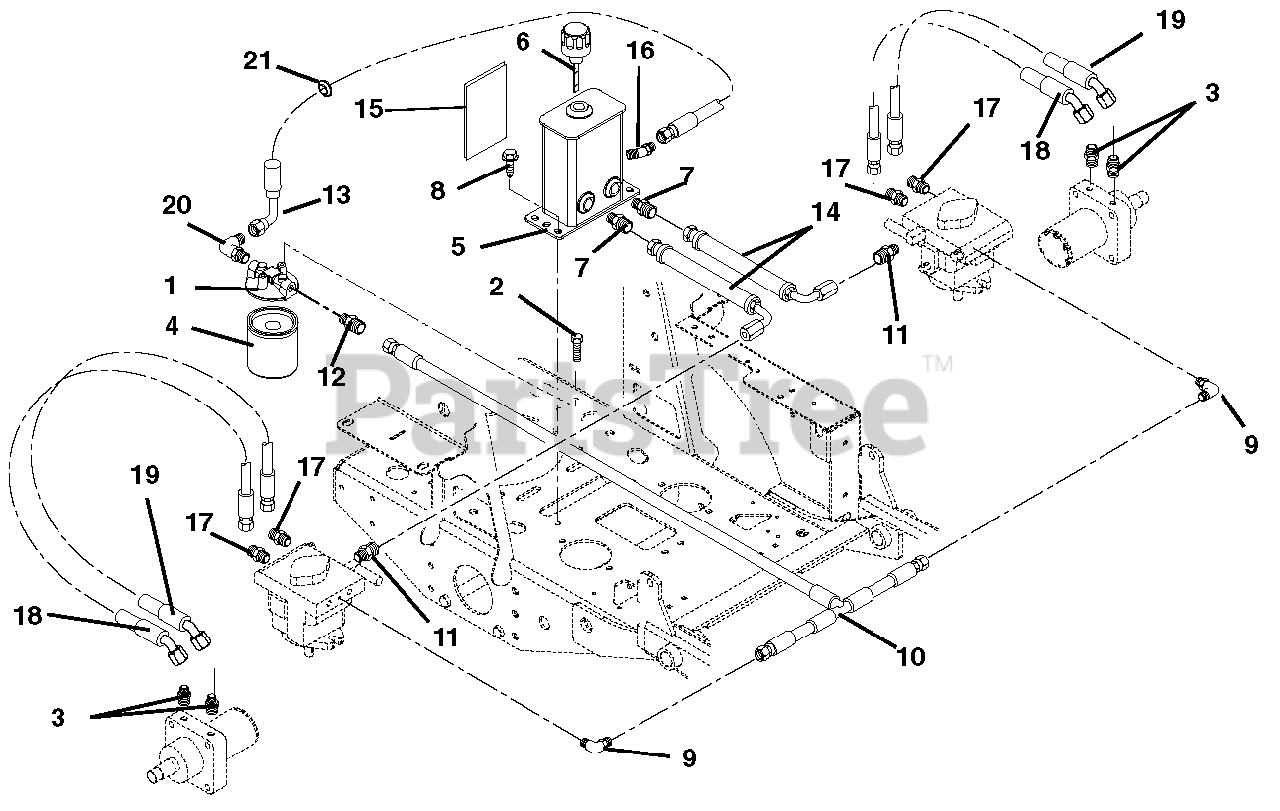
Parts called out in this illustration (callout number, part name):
1	Head, Filter
2	Bolt, Hex .25-20 x .50 Grade 5
3	Adapter, Hydraulic
4	Oil Filter
5	Weldment, Formed Hydraulic Tank - 3 Port
6	Breather Dipstick
7	Fitting, Hydraulic Straight M8O-M4F
8	Screw, Tapping .38-16 x .50 Hex Washer Head
9	Adapter, Hydraulic 8MB-12FPX90
10	Hose, Hydraulic .50 to .38 Tee Assembly
11	Fitting, Hydraulic (4-6 F5OLO)
12	Adapter, Face Seal 8 x 8 .50 O-Ring
13	Hose, Hydraulic .50-11-OK F8F0-F8F9
14	Hose, Hydraulic
15	Shield, Heat 5.50 x 4.50
16	Adapter, Face Seal 8x8 1/2 O-Ring 8 F5OLO, Steel
17	Fitting, Hydraulic
18	Hose, Hydraulic .50-11-3K
19	Hose, Hydraulic .50-12-3K
20	Fitting, Hydraulic EL M8F-M80
21	Grommet, 1.25ID x 1.50OD
